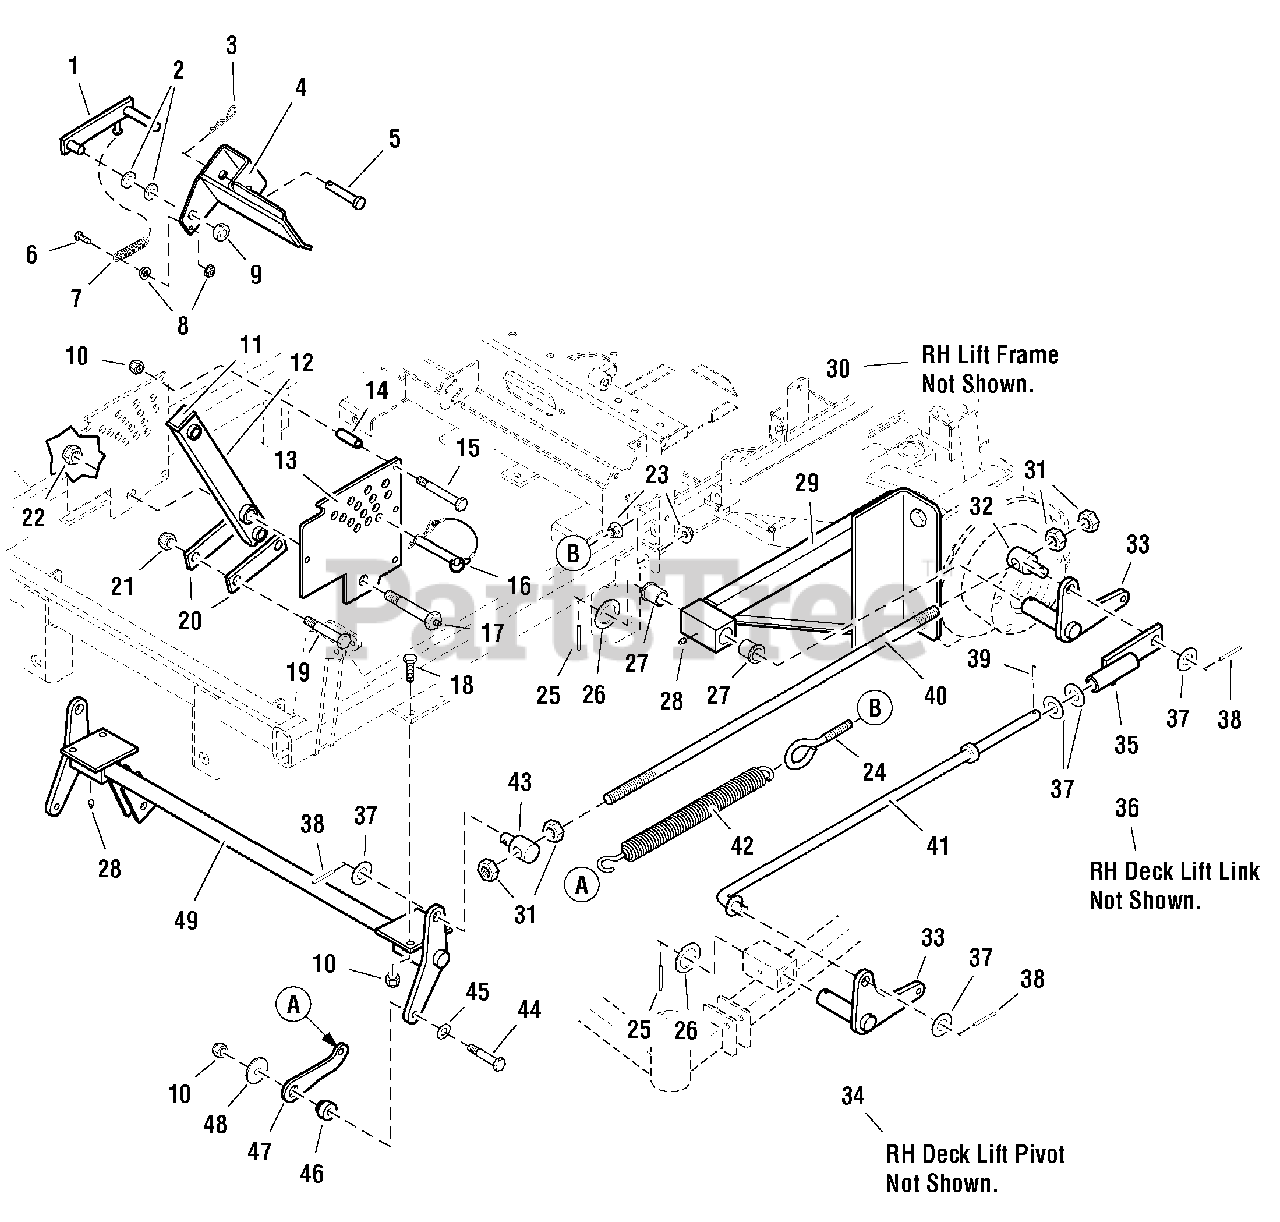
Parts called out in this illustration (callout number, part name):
1	DECK LIFT LOCK
2	WASHER, 1/2" SAE
3	HAIRPIN CLIP
4	SAFETY WALK, 4.50 X 3.50
4	DECK LIFT PEDAL
5	PIN, Clevis, 1/2 x 2-1/2
6	BOLT, 1/4-20 x 3/4
7	SPRING, Extension
8	NUT, 1/4-20 Hex Serrated Flange
9	COLLAR, Split, 1/2
10	NUT, 3/8-16 Hex Nylon Lock
12	ARM, Deck Lift Pivot
13	DECK HEIGHT PLATE
14	SPACER, .38 x .50 x 1.56
15	BOLT, 3/8-16 x 2-3/4
16	PIN, 1/2 x 3-1/2 w/ Lanyard
17	LIFT PIVOT BOLT
18	BOLT, 3/8-16 x 1-1/4
19	BOLT, 1/2-20 x 3
20	DECK LIFT LINK
21	NUT, 1/2-20 Hex Nylon Lock
22	NUT, 5/8-11 Hex Jam Nylon Lock
23	NUT, 3/8-16 Hex Serrated Flange
24	EYEBOLT, 3/8-16 x 1-1/2
25	PIN, Roll, 3/16 x 1-1/2
27	BUSHING, Flange
28	GREASE FITTING
29	LIFT FRAME ASSEMBLY - LH, Complete
30	LIFT FRAME ASSEMBLY - RH, Complete
31	NUT, 5/8-11 Hex
32	SPRING ROD PIVOT
33	DECK LIFT PIVOT - LH
34	DECK LIFT PIVOT - RH
35	DECK LIFT LINK - LH
36	DECK LIFT LINK - RH
37	WASHER, 5/8" SAE
38	PIN, Spring, 3/16 x 1-1/4
39	PIN, Roll, 3/16 x 3/4
40	DECK ADJUSTMENT ROD
41	DECK LIFT ROD
42	DECK LIFT SPRING
43	SPRING ROD PIVOT
44	BOLT, 3/8-16 x 2
45	WASHER, 3/8" SAE
46	DECK PIVOT BUSHING
47	SPRING LINK
48	WASHER, 3/8 x 2
49	DECK LIFT SHAFT & MOUNT ASSEMBLY
